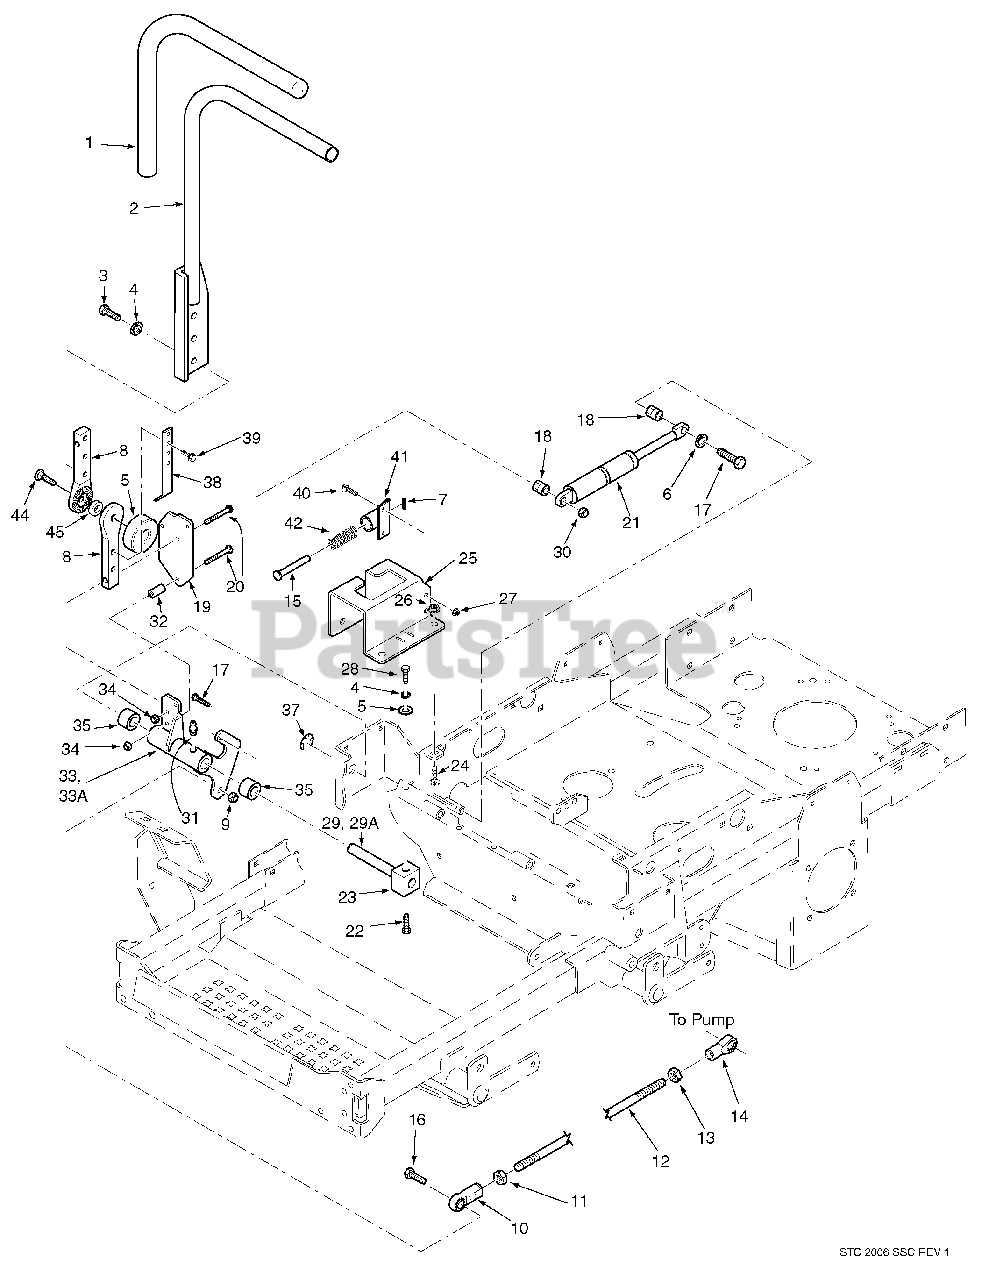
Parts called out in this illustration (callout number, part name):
1	Grip, Control Lever
2	Handle Bar, LH
3	Bolt, Hex Hd. 5/16-18 x 1"
4	Lockwasher, 5/16"
6	Flatwasher, 5/16 (.375 x .875 x .083")
7	Roll Pin, Spring 5/32 x 3/4"
8	Pivot, Control Lever
9	Nut, Elastic Stop 3/8-16
10	Rod End, 3/8-24 RH Female
11	Nut, 3/8-24 RH Thread
12	Rod, Pump Control Linkage
13	Nut, 3/8-24 UNF-2B LH Thread
14	Rod End, 3/8-24 LH Thread
15	Pin Retainer
16	Bolt, Hex Hd. 3/8-16 x 1-1/2"
17	Bolt, Hex Hd. 5/16-18 x 1-3/4"
18	Spacer, Pump Damper
19	Plate, Control Lever
20	Bolt, Hex Hd. 5/16-18 x 2"
21	Gas Damper
22	Bolt, Hex Hd. 3/8-16 x 1"
23	Block, Clamping
24	Bolt, Carriage, 5/16-18 x 3/4"
25	Control Plate - LH w/Decal
26	Nut, Serr., Flng., 5/16-18
27	Nut, Elastic Stop 1/4-20
28	Bolt, Hex Hd. 3/8-16 x 3/4"
29	Shaft, Steering Control
30	Nut, Elastic Stop 5/16-18
31	Grease Fitting, 1/4-28 Self Tap
32	Spacer, Control
33	Control Lever Assy RH
34	Nut, Elastic Stop 5/16-18
35	Bushing
36	Flatwasher, 3/4 (.766 x 1.25 x .059")
37	Retaining Ring, 3/4" Ext.
38	Bracket, Switch Actuator
39	Bolt, Hex Serr. Flng. 5/16-18 x 3/4"
40	Bolt, Carr. 1/4-20 x 3/4"
41	Bracket, Control Return
42	Spring
43	Pin Retainer
44	Bolt, Carriage 5/16-18 x 1-1/2"
45	Rubber Spacer
